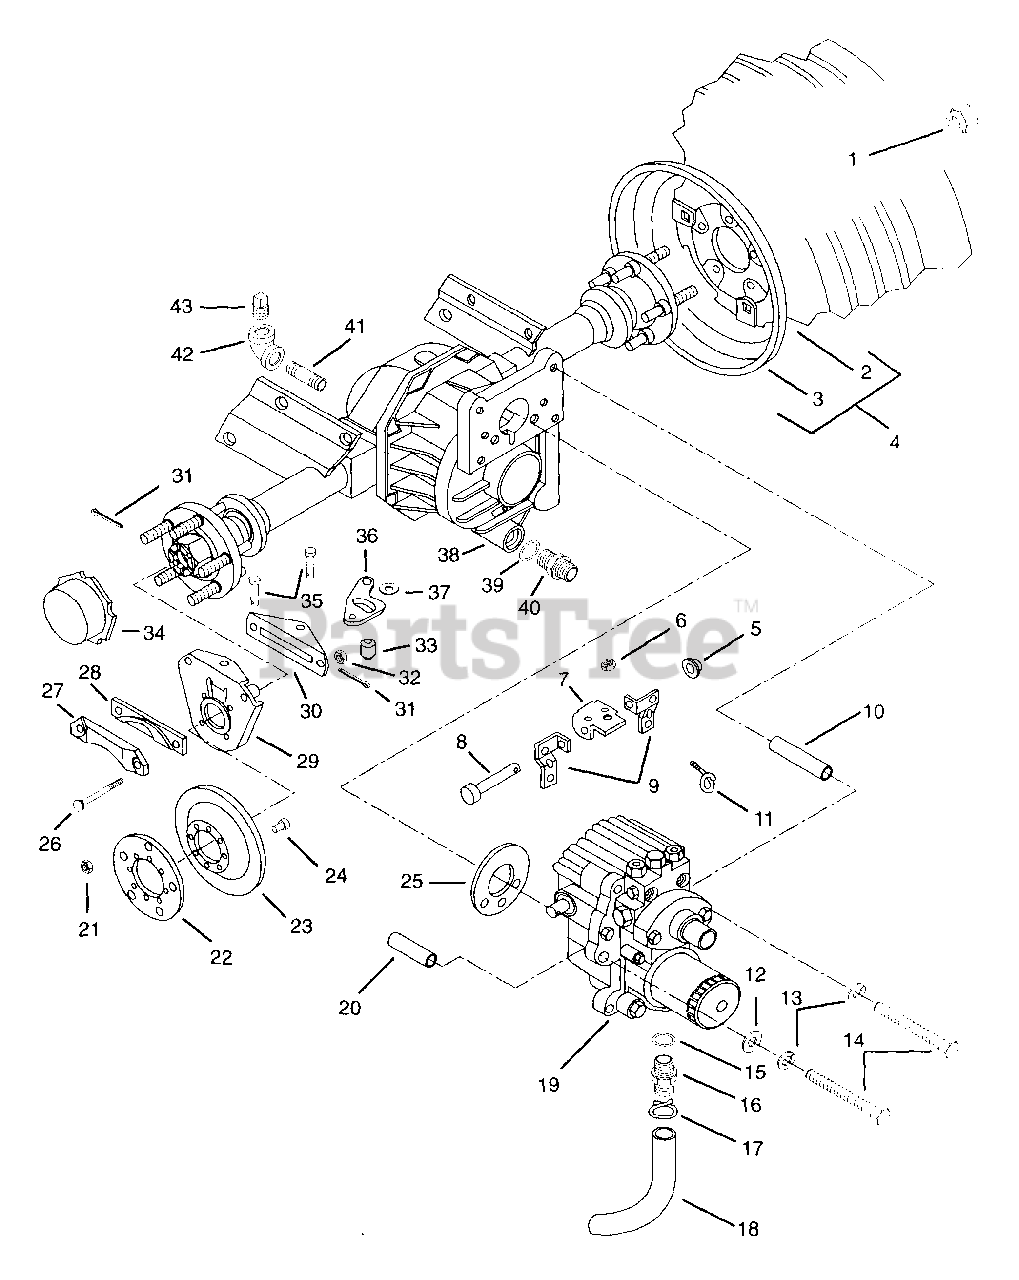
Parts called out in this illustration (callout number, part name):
1	NUT-LUG .437-20 YWZC
4	T/WHL ASSY 10.50X23
5	NUT-PUSH .312 DIA. PAL
6	NUT-LK-FLG .250-20 PL
8	CLEVIS PIN
9	SUPPORT
10	SPACER .379X.625X3.480
11	CABLE SUPPORT
12	WSHR-FL-STL .390X.750X.125 PL
13	WSHR-LK .375X.094 MED PL
14	BLT-HEX .38-16X5.00 PL GR2
15	O-RING .250X.943X.103
16	FTG-ADPTR 88-14
17	HOSE CLAMP #15 .906/.968
18	HOSE .62X.91X8.00
19	TRANSMISSION ASS'Y
20	SPACER .379X.625X3.220
21	GROMMET
22	CARRIER
24	SCR-TAP .250-20X.37 HWH PL TR
26	BLT-RDHDSQNK .38-16X3.50 GR5PL
27	CALIPER PLATE
28	FRICTION PLATE
29	PLATE, CALIPER MOUNTING
30	PRESSURE PLATE
31	PIN-COTR .09X.75 PL
32	NUT-LK-NYL .375-16 PL
34	REAR HUB CAP
35	PIN-CLEV .371X1.62 YWZC
36	BRAKE ARM
37	WSHR-FL-STL .323X.625X.062 PL
38	REAR AXLE & SUPPORTS
39	O-RING .924X1.156X.116
40	CONNECTOR
41	PIPE NIPPLE
42	ELBOW 1/2 X 90
43	PIPE PLUG
